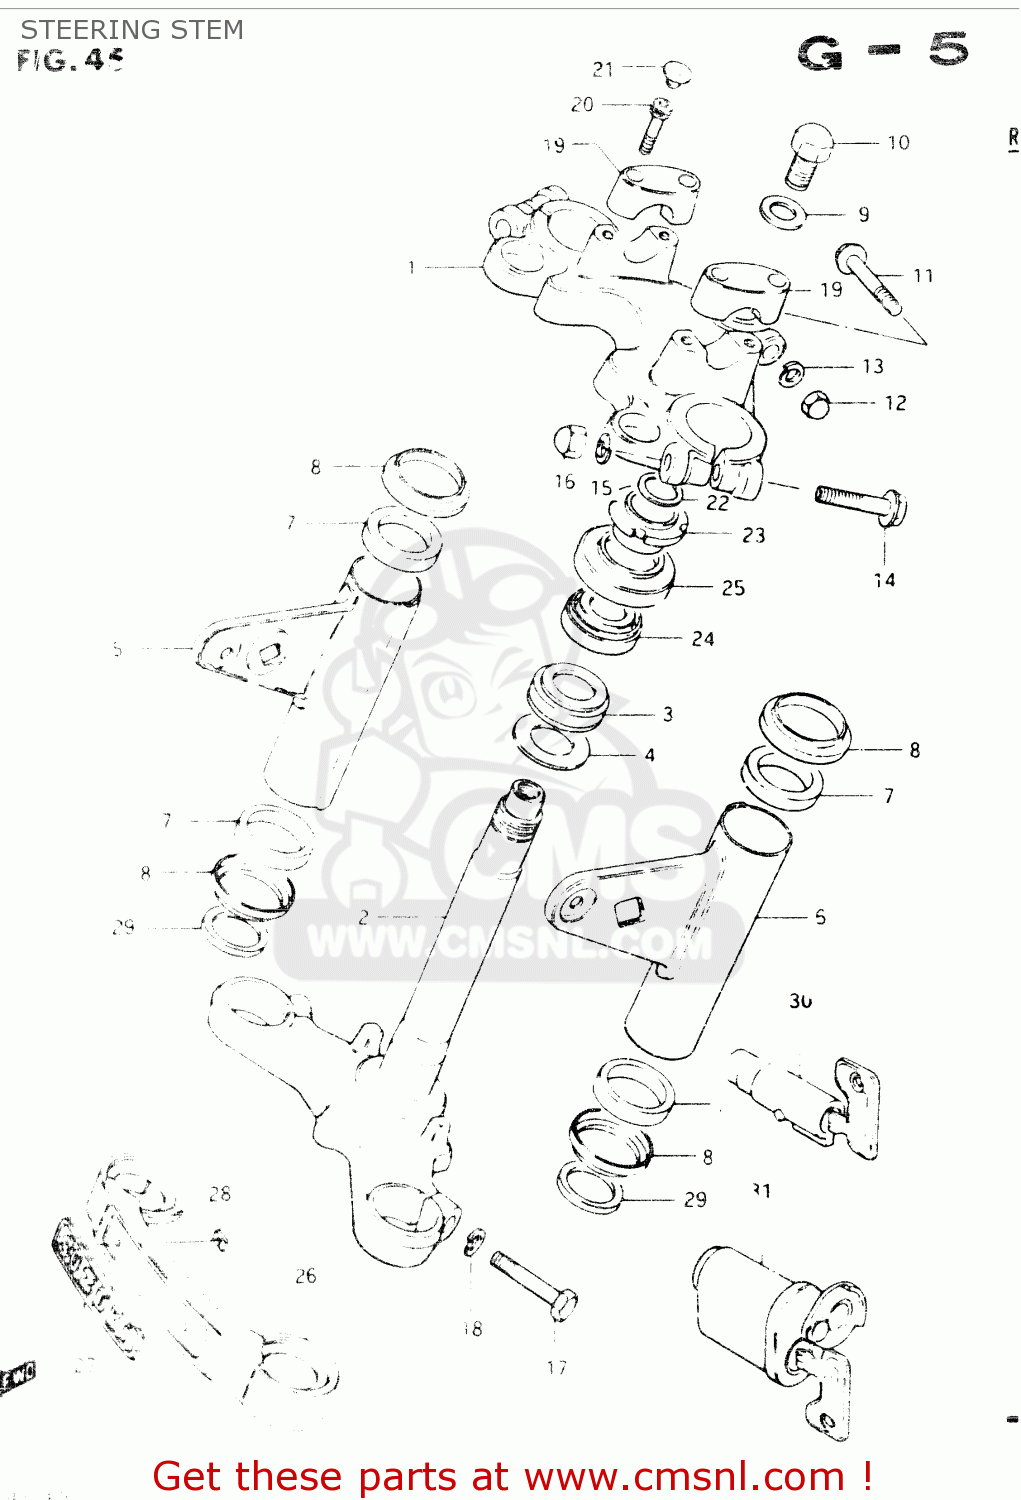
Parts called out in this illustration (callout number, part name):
1	HEAD,STEERING STEM
2	STEM,STEERING
3	BEARING
4	WASHER,THRUST
5	BRACKET,HEADLAMP,RIGHT
6	BRACKET,HEADLAMP,LEFT
7	CUSHION,HEADLAMP BRACKET
8	CAP,HEADLAMP BRACKET
9	WASHER (12.5X27X1.6)
10	BOLT(12X20)
11	BOLT, UPPER
12	NUT,M8X1.25X12
13	WASHER,LOCK,8.
14	BOLT
15	LOCK WASHER
16	NUT
17	BOLT
18	WASHER,LOCK
19	HOLDER,HANDLEBAR(BLACK)
20	BOLT, REAR (8X30)
21	CAP(OD:14.5)
22	WASHER(18.5X24X1)
23	NUT,STEERING STEM
24	TAPER,ROLLER BEARING
25	DUST SEAL,STEERING UPR
26	COVER,FRONT FORK
27	EMBLEM,FR FORK COVER
28	NUT
29	SEAT,HEADLAMP BRACKET LWR
30	LOCK ASSEMBLY,STEERING (NEI
31	LOCK ASSY, STEERING (NEIMAN TYPE EXECUTE
